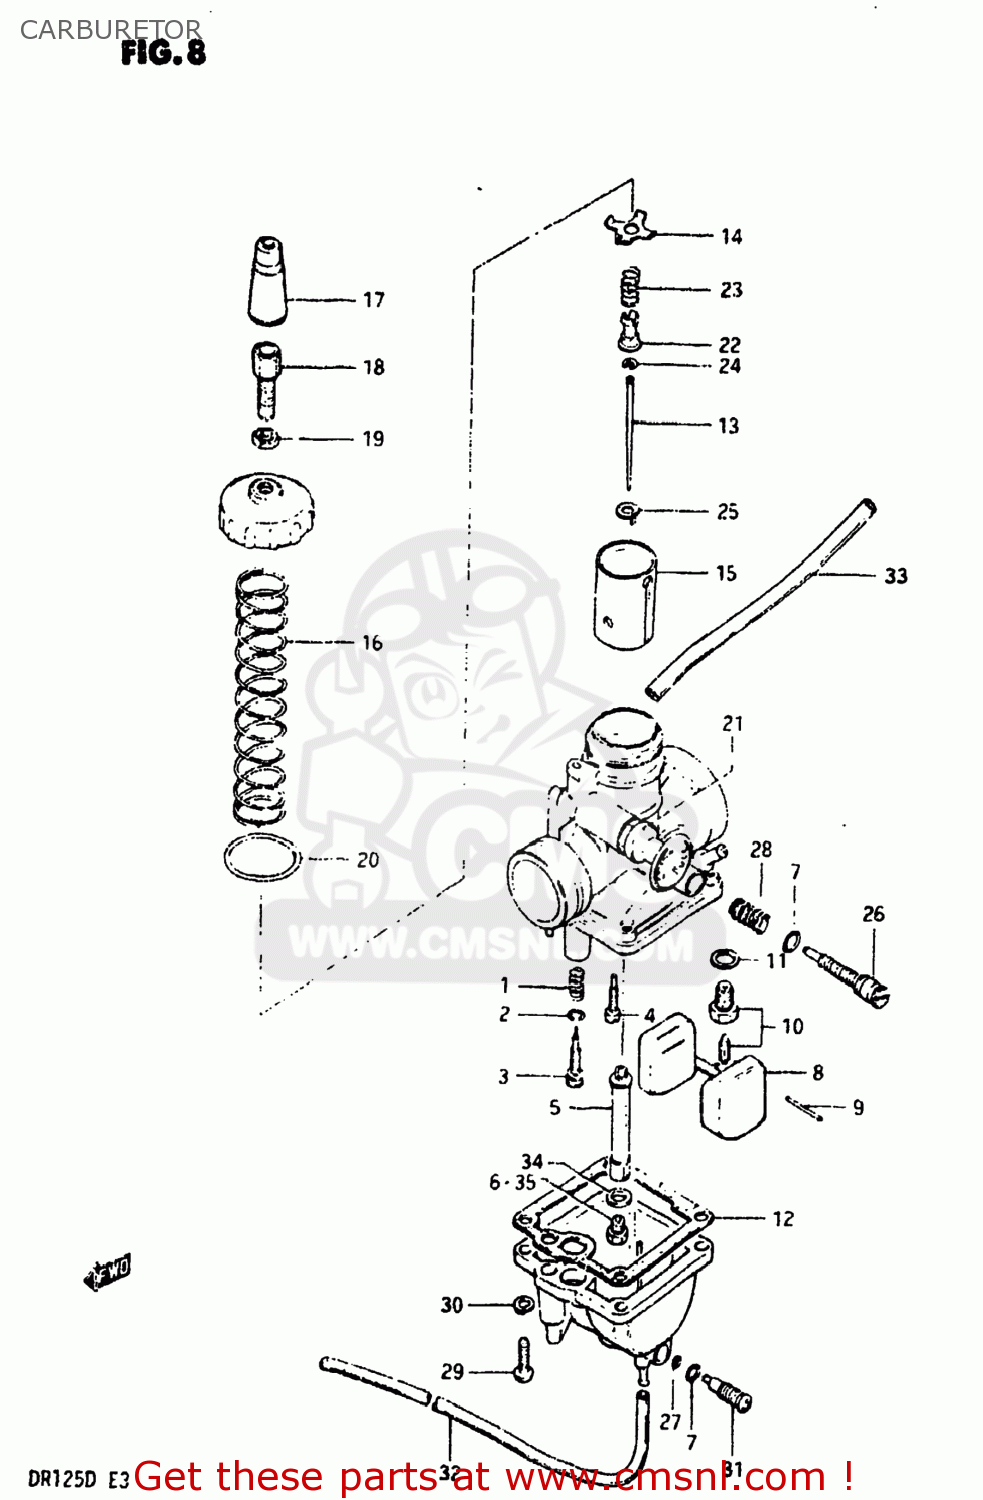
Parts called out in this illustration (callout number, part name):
0	CARBURETOR ASSY
1	SPRING,THROTTLE ADJUST
2	O-RING
3	SCREW,PILOT AIR
4	JET,PILOT
5	JET,NEEDLE
6	JET,MAIN
7	O-RING
8	FLOAT
9	PIN,FLOAT
10	VALVE ASSY,NEEDLE(ID:2.0)
11	GASKET,NEEDLE VALVE SE
12	GASKET,FLOAT CHAMBER (NAS)
13	NEEDLE JET
14	PLATE,THROTTLE VALVE
15	VALVE,THROTTLE
16	SPRING,THROTTLE VALVE
17	CAP
18	ADJUSTER,CABLE
19	NUT,CABLE ADJUSTER LOCK
20	O-RING,MIXING CHAMBER
21	VALVE ASSEMBLY,STARTER
22	HOLDER,NEEDLE
23	SPRING,NEEDLE JET
24	E-RING
25	RECEIVER,NEEDLE
26	SCREW,THROTTLE STOP
27	O-RING,DRAIN PLUG
28	SPRING,THROTTLE SCREW
29	SCREW
30	LOCK WASHER
31	PLUG,DRAIN
32	HOSE
33	HOSE
34	WASHER,MAIN JET
35	JET,MAIN
